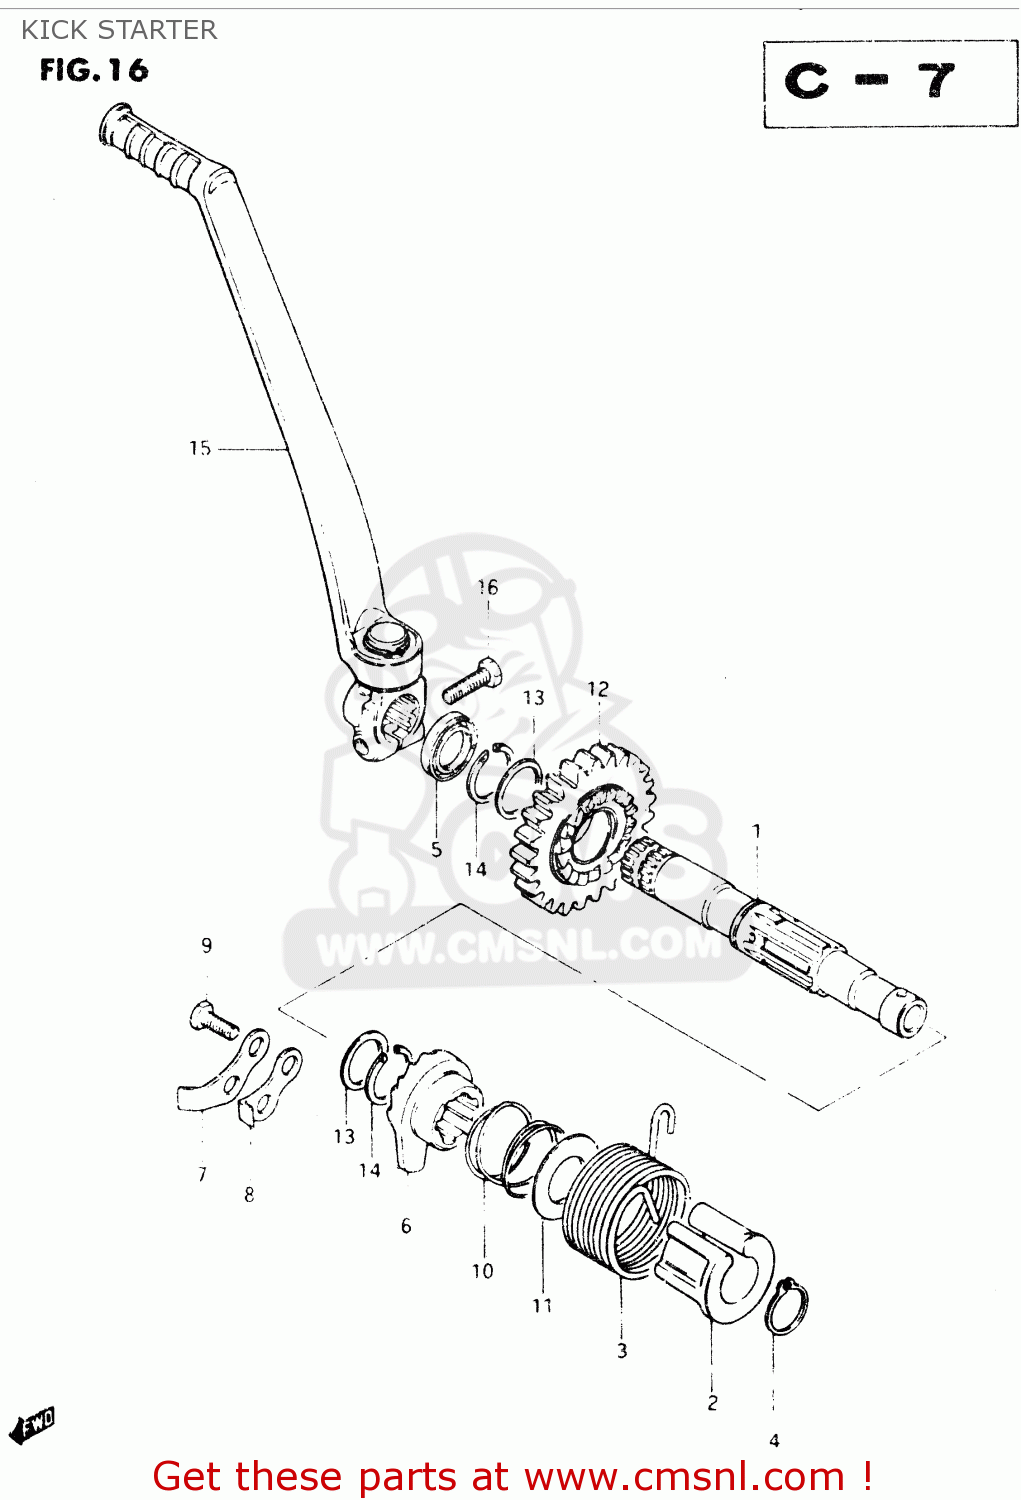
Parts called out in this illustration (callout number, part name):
1	SHAFT,KICK STARTER
2	GUIDE,KICK STARTER SFT SPRING
3	SPRING
4	CIRCLIP
5	SEAL,OIL(20X27X5)
6	STARTER,KICK
7	GUIDE,KICK STARTER
8	STOPPER,KICK STARTER
9	BOLT
10	SPRING
11	WASHER
12	GEAR,KICK STARTER DRIIVE
13	SHIM
14	CIRCLIP
15	LEVER ASSEMBLY,KICK STARTER
16	BOLT 8X25
